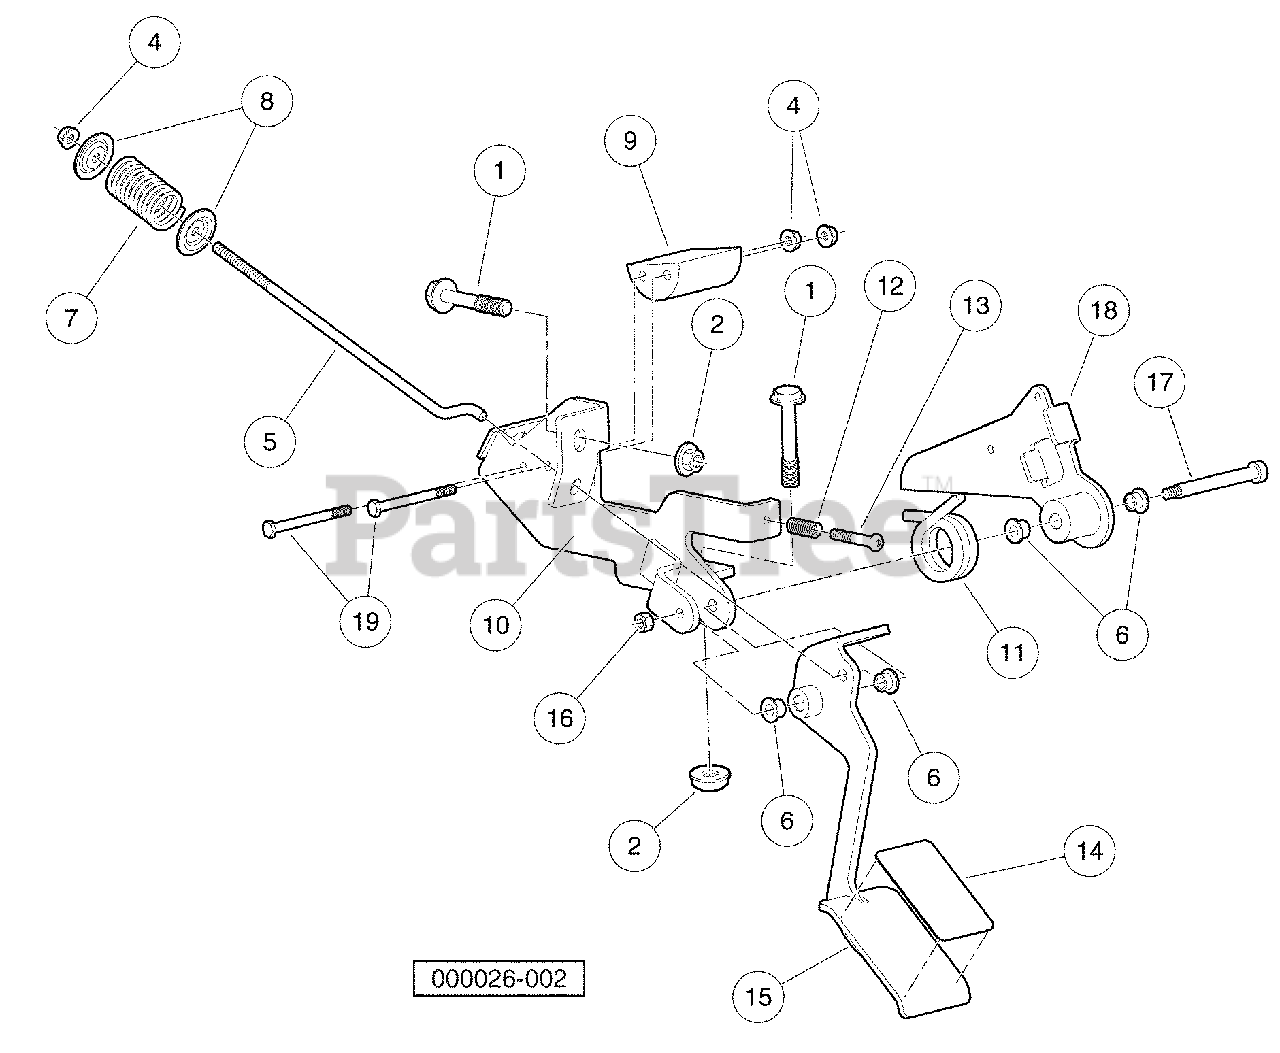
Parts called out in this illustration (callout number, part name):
1	Bolt Flanged Head, M8 X 1.25 X 65.
2	Lock Nut, Flg M8 X 1.25 Nylon.
3	Asm, Accelerator Pedal
4	Nut-m6x1.0 Flng All Mtl Lock
5	Pullrod, Spring, Compression
6	Bushing, Greaseless
7	Spring, Comp, Pedal, Pullrod
9	Guide, Cable, Accelerator.
10	Weldment, Bracket, Pedal.
11	Spring, Torsion
12	Spring, Stop, Pedal.
13	Bolt, Stop, Pedal
14	Pad, Grip Tape, Accelerator.
15	Weldment, Pedal, Accelerator
16	Nut M6x1 Mech Def Center.
17	Bolt, Shoulder, M8 X 70, Hc.
18	Weldment, Lever, Lost Motion
19	Bolt, M6 X 1 X 70
